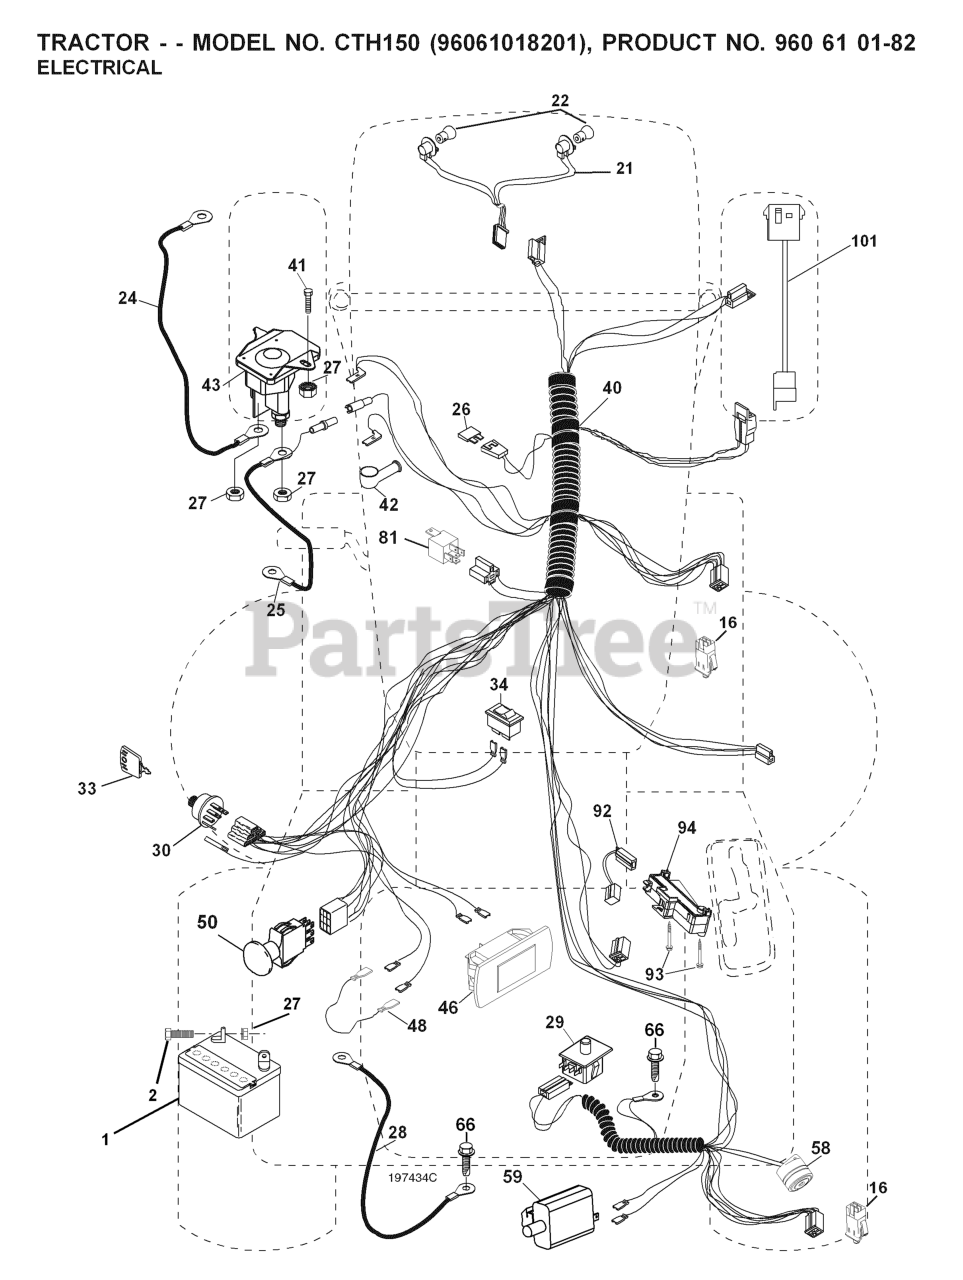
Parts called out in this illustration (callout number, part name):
1	BATTERY 12V .35 AMP
2	BOLT.HEX.1/4.X.3/4.DICHROMATE
16	SWITCH INTERLOOK PUSH-IN
21	HARNESS ASSY LIGHT
24	BATTERY CABLE GT
25	CABLE BATTERY
26	FUSE 20AMP
27	NUT
28	CABLE GROUND
29	SWITCH.SEAT.DP W/RAMPS
30	SWITCH.IGN.DELTA.W.LGH.ROS
33	KEY MLD GEN DELTA
40	RP HARNESS.IGN.ELECT.REG.CRD
41	BOLT
42	TERMINAL COVER
43	SOLENOID.W/BRASS.PLUNGER
46	RP.GUAGE.SRVCMNDR.HRMTR.
48	ADAPTER.AMMETER
50	RP.PTO.SWITCH.8 TERMINAL.BLACK
58	BUZZER
59	.WITCH.FULL BAGGER.INDICATOR
81	RELAY.ASSY.T
92	HARNESS.PIGTAIL.CONSLE
93	SCREW.PLASTITE
94	MODULE.REVERSE.ROS
101	PIGTAIL.MATNLK.NEW.HAR
